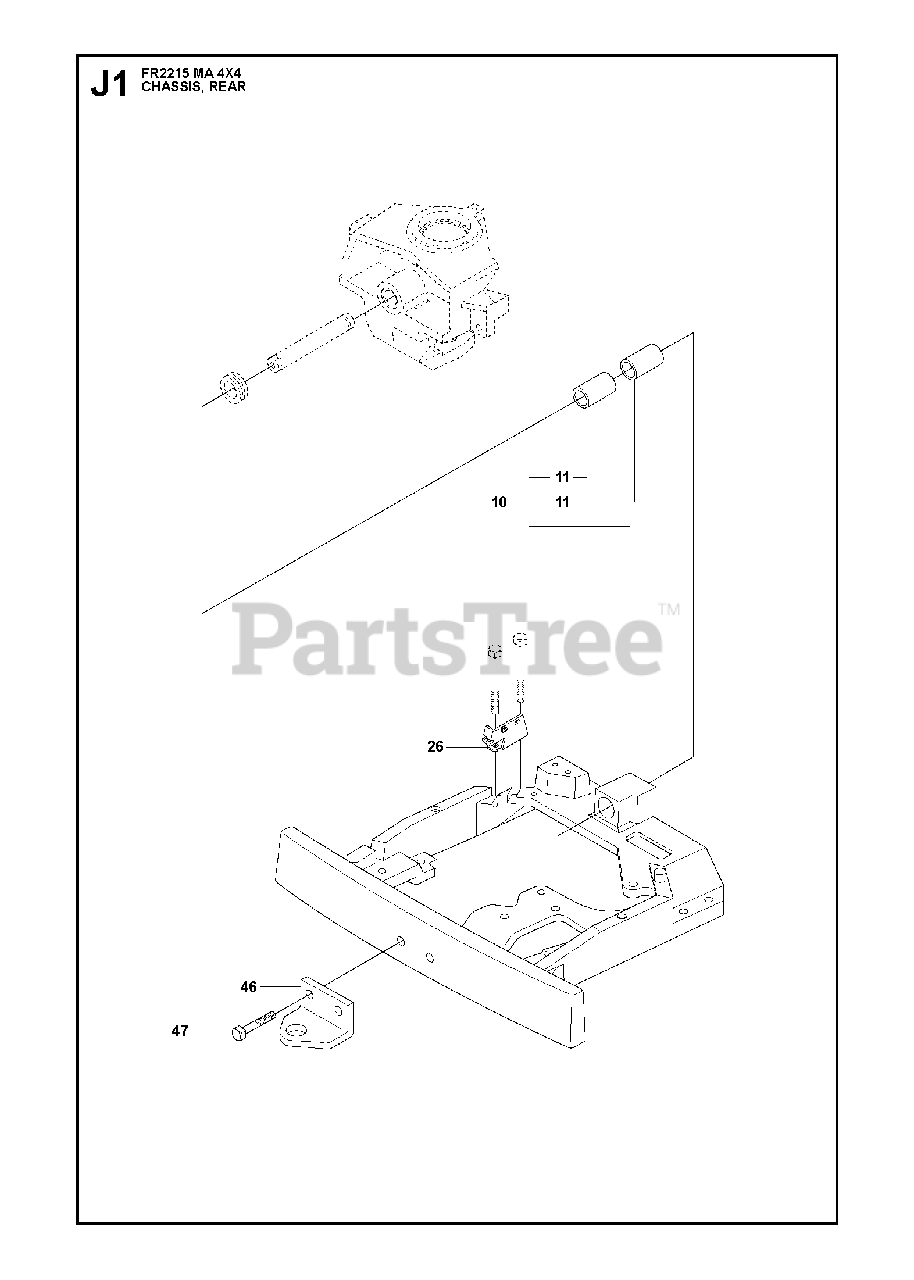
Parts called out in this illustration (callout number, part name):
11	BUSHING
46	DRAW RING
47	SCREW M10X25
